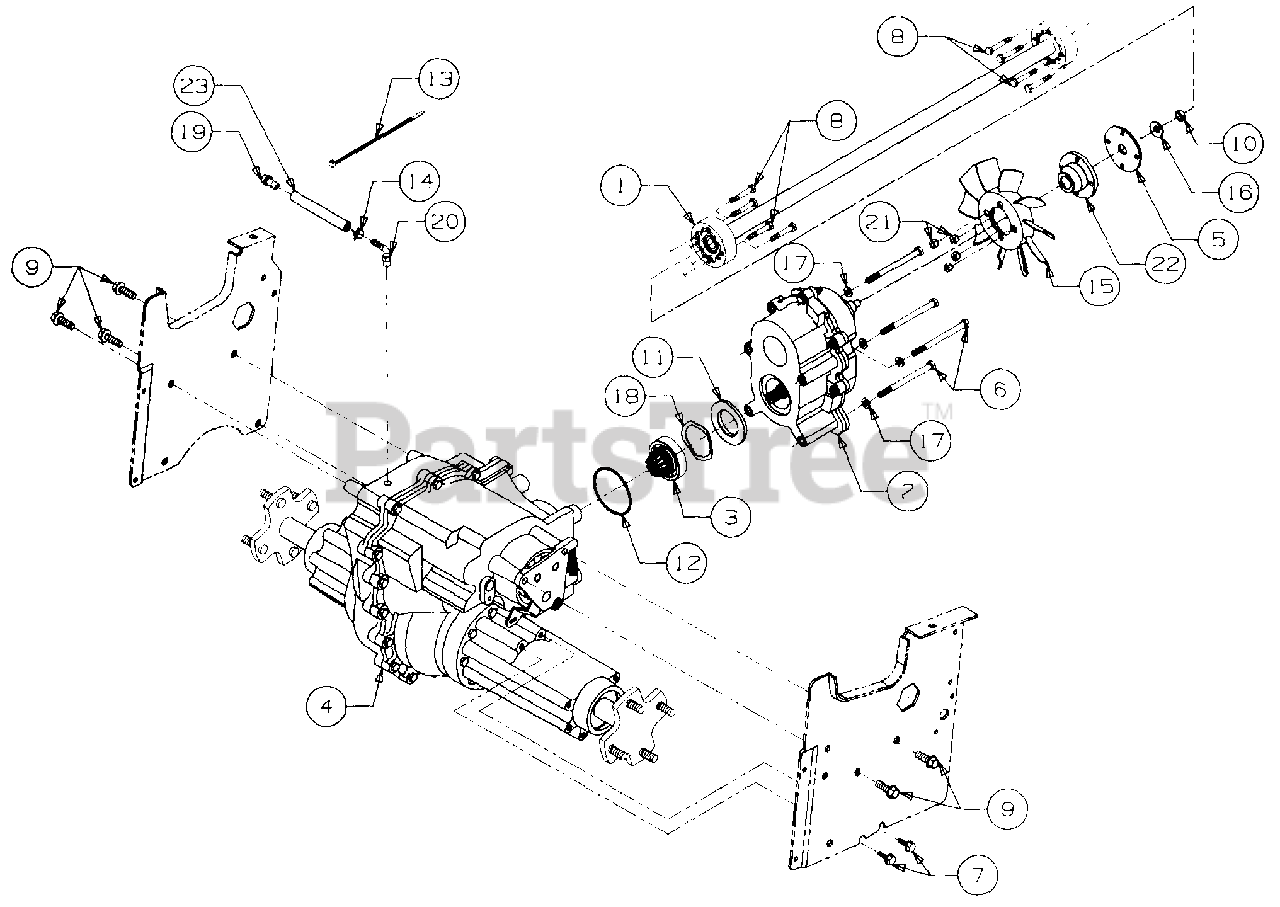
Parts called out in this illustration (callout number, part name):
1	Shaft Assy, Drive, 29.06 Lg
2	Clutch Assy
3	Pinion Assy, Input
4	Transmission Assy, 6-Speed
5	Plate, Drive Shaft Spacer
6	Screw, Hex Cap, 5/16-18 x 4.0 Lg GR5
7	Screw, Hex Wash Sf-Tapp 5/16-18 x .75 Lg
8	Bolt, Hex Patch, 1/4-20 x 1.62 Lg GR5
9	Screw, Hex Wash Tapp 3/8-16 x 1.25 Lg
10	Nut, Hex Center Lock Jam 3/8-24
11	Plate, Clutch Output Shim
12	O-Ring, 2.75 x .103
13	Tie, Self-Clinch Cable
14	Clamp, Hose
15	Fan, 10 Blade Cooling
16	Washer, Bell, .380 x .88 x .062 Thk
17	Washer, Lock, 5/16
18	Washer, Spring Wave, 1.96 x 2.44 x .06 Thk
20	Fitting, Elbow
21	Nut, Fan, 1/4-20
22	Adapter, Clutch
23	Line, Fuel, 7 in. Lg
